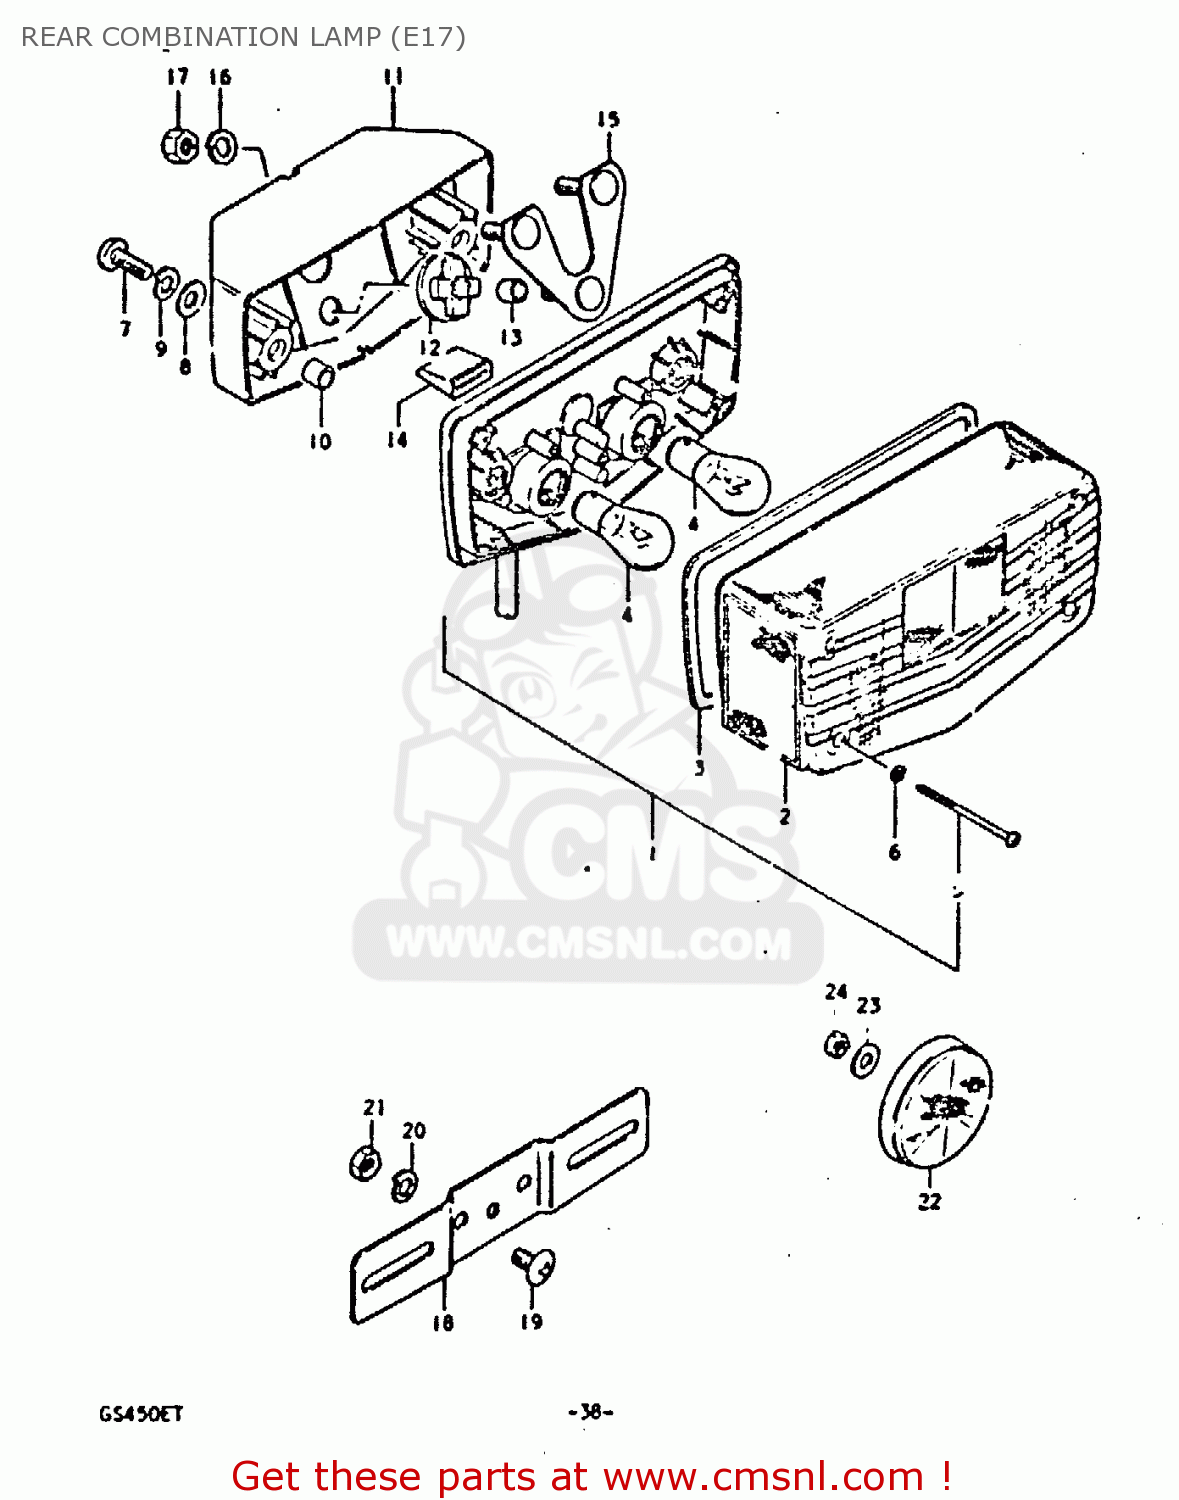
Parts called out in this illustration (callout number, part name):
1	LAMP UNIT, REAR COMBINATION
2	LENS
3	GASKET,REAR COMBINATION LAMP LENS (NAS)
4	BULB 12V21/5W
5	SCREW
6	GASKET (NAS)
7	SCREW
8	WASHER
9	LOCK WASHER
10	SPACER,REAR COMBINATION LAMP
11	BRACKET UNIT,TAIL LAMP
12	CUSHION,REAR COMBINATION LAMP
13	SPACER,REAR COMBINATION LAMP
14	CUSHION,REAR COMBINATION LAMP
15	PLATE,REAR COMBINATION LAMP
16	LOCK WASHER
17	NUT
18	PLATE,RR LICENSE
19	SCREW
20	LOCK WASHER
21	NUT
22	REFLEX REFLECTOR,RR
23	WASHER
24	NUT
